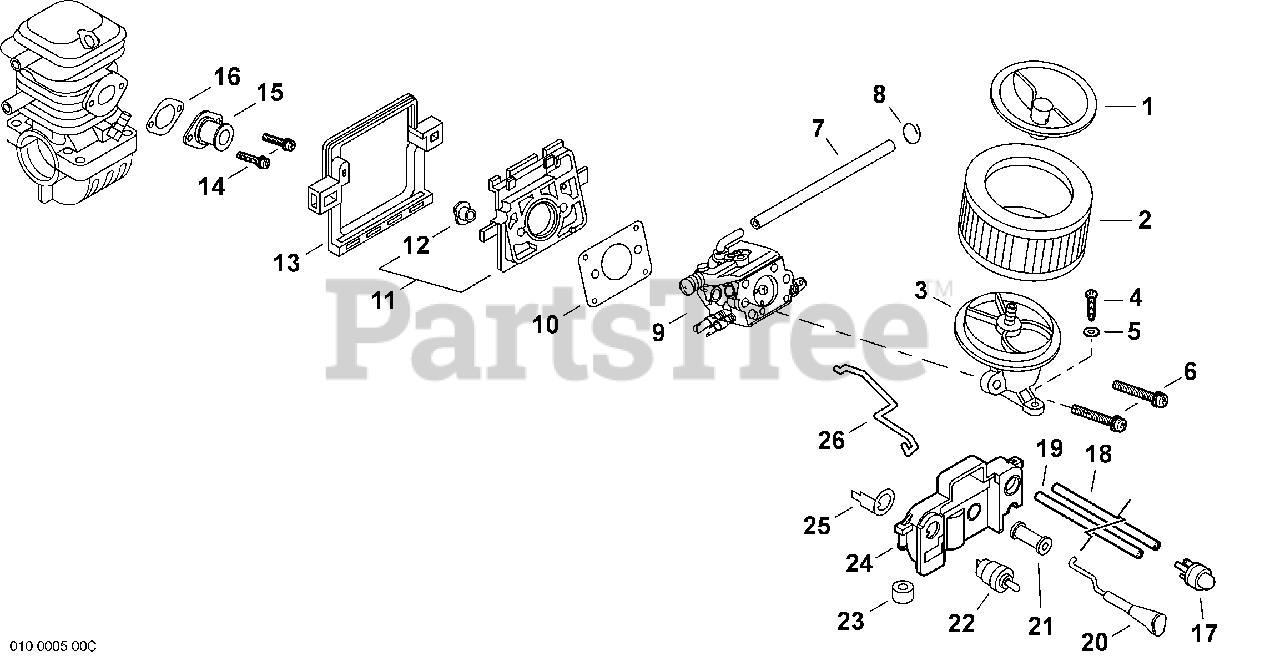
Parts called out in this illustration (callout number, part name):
1	CAP ASSY, AIR FILTER
2	FILTER, HEAVY DUTY AIR
3	ADAPTOR, INTAKE
4	SCREW 5×20
5	WASHER, FLAT 5.5×10×0.8
6	SCREW 5×50
7	PIPE, PULSE 2.4×6×105
8	CLIP Ø6
9	CARBURETOR - WT-980
10	GASKET, INTAKE
11	INSULATOR SET, INTAKE
13	CUSHION
14	SCREW 5×14
15	BELLOWS, INTAKE
16	GASKET, INTAKE
17	BULB, PURGE
18	PIPE 2.4×5×200 BLACK
19	PIPE 2.4×5×150 BLACK
20	ROD, CHOKE
21	GROMMET, CHOKE
22	SWITCH, ON-OFF
24	BRACKET, SWITCH
25	TERMINAL, GROUND
26	ROD, THROTTLE
